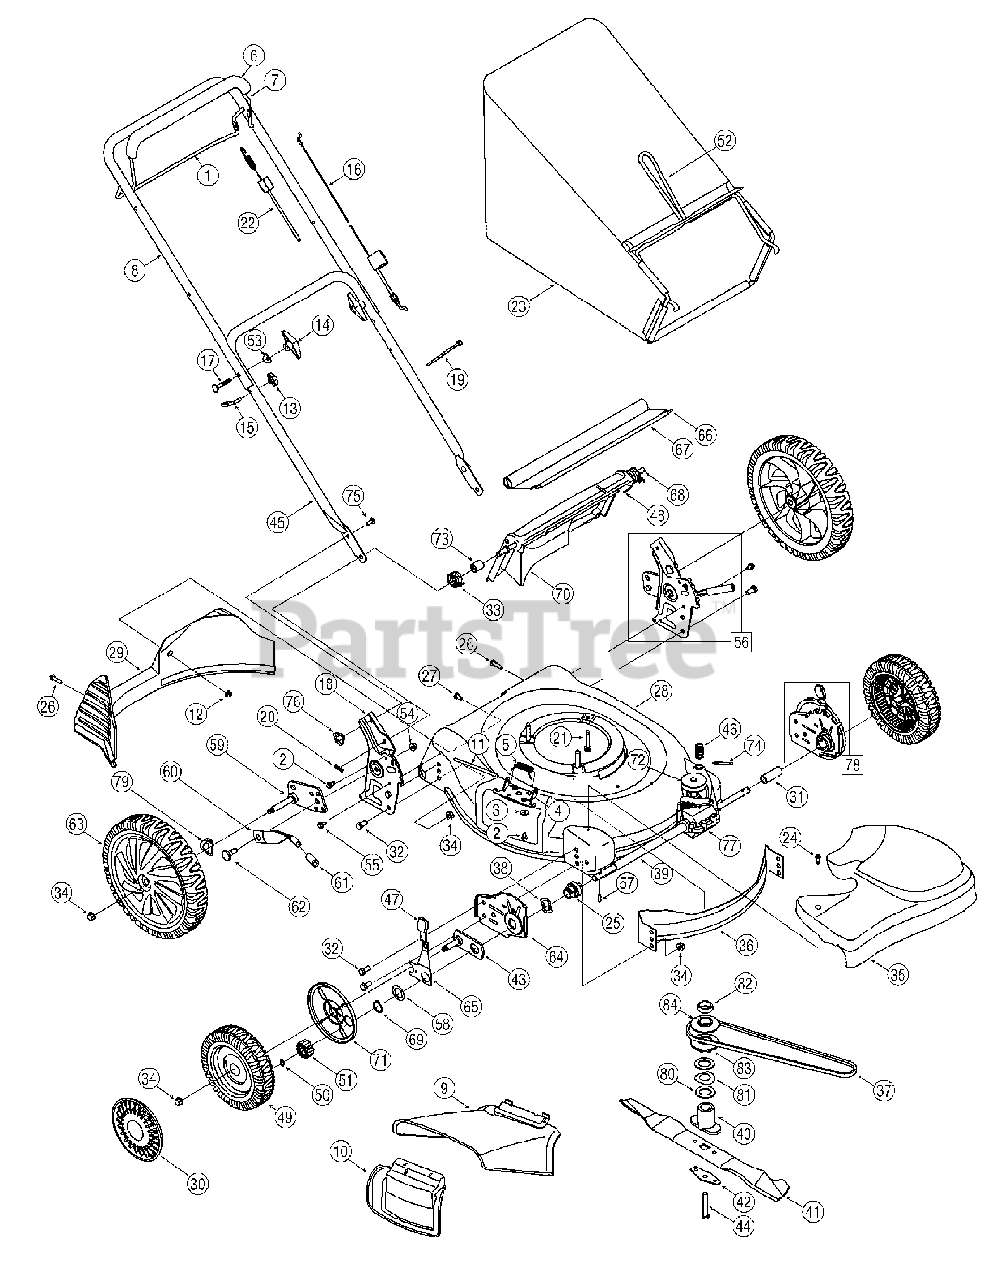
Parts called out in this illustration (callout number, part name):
1	Drive Control
2	TT Screw 1/4-20 x 0.5
3	Bell Washer.265 x 0.75
4	Deflector Chute Adapter
5	Torsion Spring
6	Deluxe Bail Cover
7	Blade Control
9	Chute Deflector
10	Mulch Plug Complete
11	Hinge Pin
12	Flange Lock Nut, 1/4-20
13	Handle Knob
14	Handle Knob
15	Eye Bolt
16	Control Cable - 37.75"
17	Carriage Bolt 5/16-18 x 2.0
18	Handle Bracket - RH
18	Handle Bracket - LH
19	Cable Tie
20	Cotter Pin
21	Self-Tapping Sems Screw
22	Drive Cable - 50.50"
23	Grassbag Assembly
24	Shoulder Screw # 12 -24
25	Front Bearing Assembly
26	Screw, 1/4-15 x 1.25
27	Screw, 1/4-20 x .500
30	Hub Cap
31	Slev. Spacer 2.1" Lg.
32	Hex Screw, 3/8-16 x.75
33	Torsion Spring - RH
34	Flange Lock Nut, 3/8-16
35	Transmission Cover
36	Front Baffle
37	V-Belt
38	Wave Washer
39	Sleeve Spacer 9.04" Lg.
40	Blade Adapter w/ Star
41	21" Mulching Blade
42	Blade Bell Support
43	Pivot Plate Assembly
44	Hex Screw 3/8-24 x 2.50
45	Lower Handle
46	Belt Tension Spring
47	Adjustment Knob
48	Torsion Spring - LH
49	Front Wheel 8 x 2.125
50	Snap Ring
51	Gear 14T RH FWD
51	Gear 14T LH FWD
53	Saddle Washer
54	Hex Flange Lock Nut 3/8-16
55	TT Scr. w/Washer 1/4-20 x.625
56	Handle Bracket Assembly - LH
56	Handle Bracket Assembly - RH
57	Dowel Pin
58	Washer
59	Pivot Arm Assembly - RH
59	Pivot Arm Assembly - LH
60	Rear Spring Lever
61	Foam Grip
62	Shoulder Scr.500 Dia. x.434
63	Rear Wheel, 12 x 2.125
64	Height Adjuster Plate - RH
64	Height Adjuster Plate - LH
65	Front Lever - RH
65	Front Lever - LH
66	Wire
67	Rear Trailing Shield
68	Pivot Rod
69	Snap Ring
70	Rear Discharge Door
71	Wheel Dust Cap
72	Input Pulley
73	Spacer.375 x.50 x 1.02" Lg.
74	Roll Pin
75	Carriage Bolt 1/4-20
76	Wing Nut
77	Transmission Assembly
78	Height Adjustment Assembly RH
78	Height Adjustment Assembly LH
79	Spring Washer, .500 x 1.00
80	Flat Washer, 1.00 x 1.75 x .107
81	Sprg Washer, 1.005 x 1.825
82	Sleeve Spacer
83	Key Half Pulley
84	Upper Half Pulley
